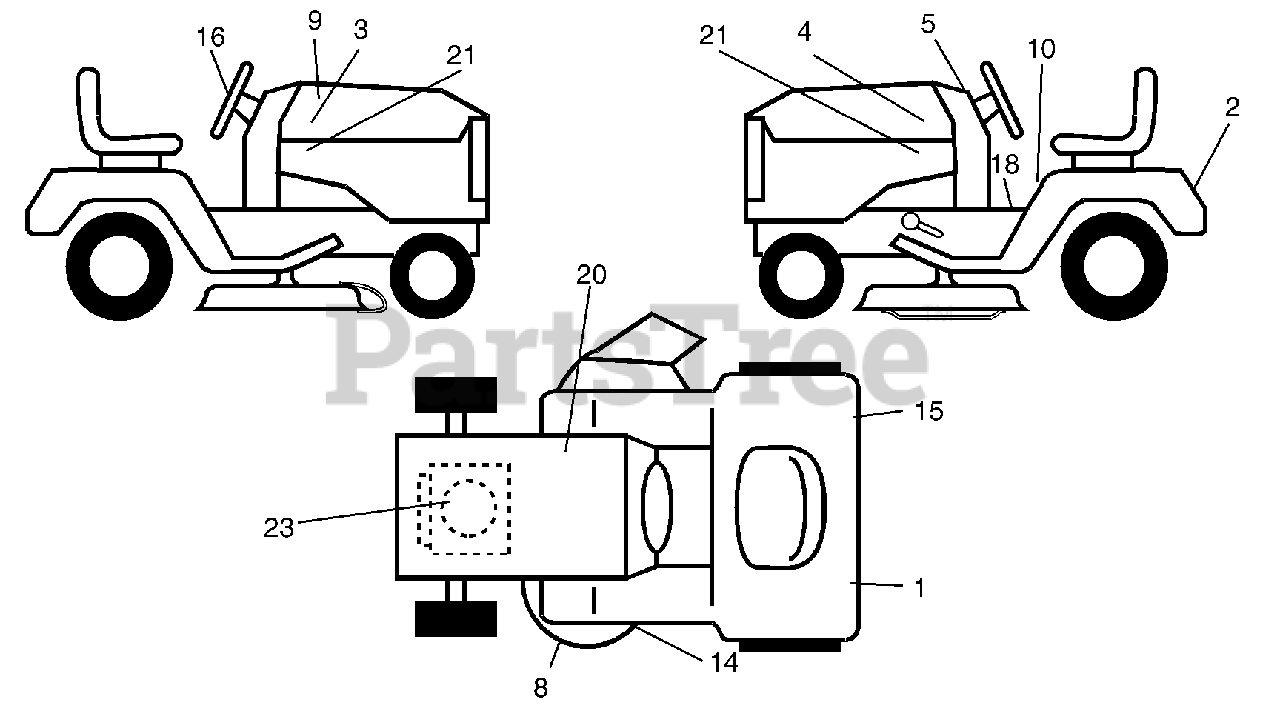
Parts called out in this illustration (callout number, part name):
1	Reflector, LH
2	Decal, Fender
3	Decal, Hood RH
4	Decal, Hood LH
5	Decal, DSHINS
8	Decal, Deck, Caution
9	Decal, Replacement Hood
10	Decal, Fender, Danger
14	Decal, V-Belt, Schematic
15	Decal, Reflector, RH
16	Decal, Steering Wheel
18	Decal, Fender Opr.
20	Decal, Battery
21	Decal, Hood, Side Panel
23	Decal, Engine
